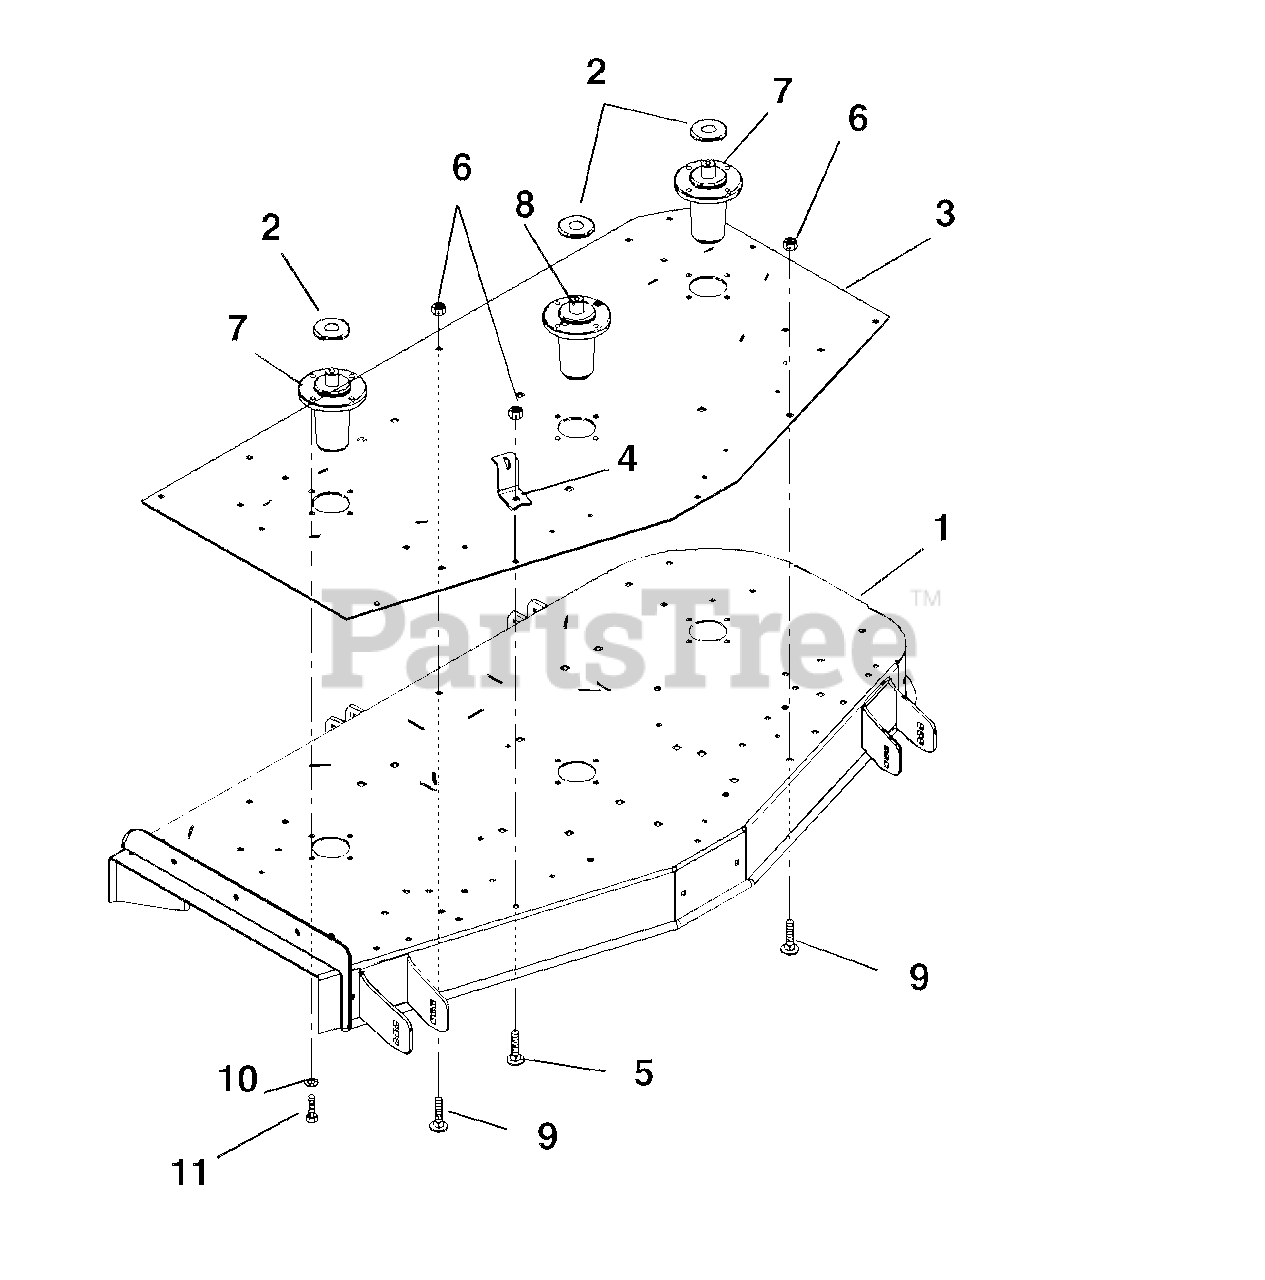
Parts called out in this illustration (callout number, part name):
1	Weldment, 60" Deck (Side Discharge)
2	Slinger-Dust
3	Plate, 60" Reinforcing
4	Anchor, Spring
5	Bolt-Round Head Square Neck .38-16 x 1.25 Grade 5
6	Nut-Locking-Nylon .38-16
7	Assembly, Spindle L-Hub
8	Spindle Assembly (Center)
9	Bolt-Round Head Square Neck .38-16 x 1.00 Grade 2
10	Washer-Locking .38 x .094
11	Bolt-Hex .38-16 x 1.00 Grade 5
